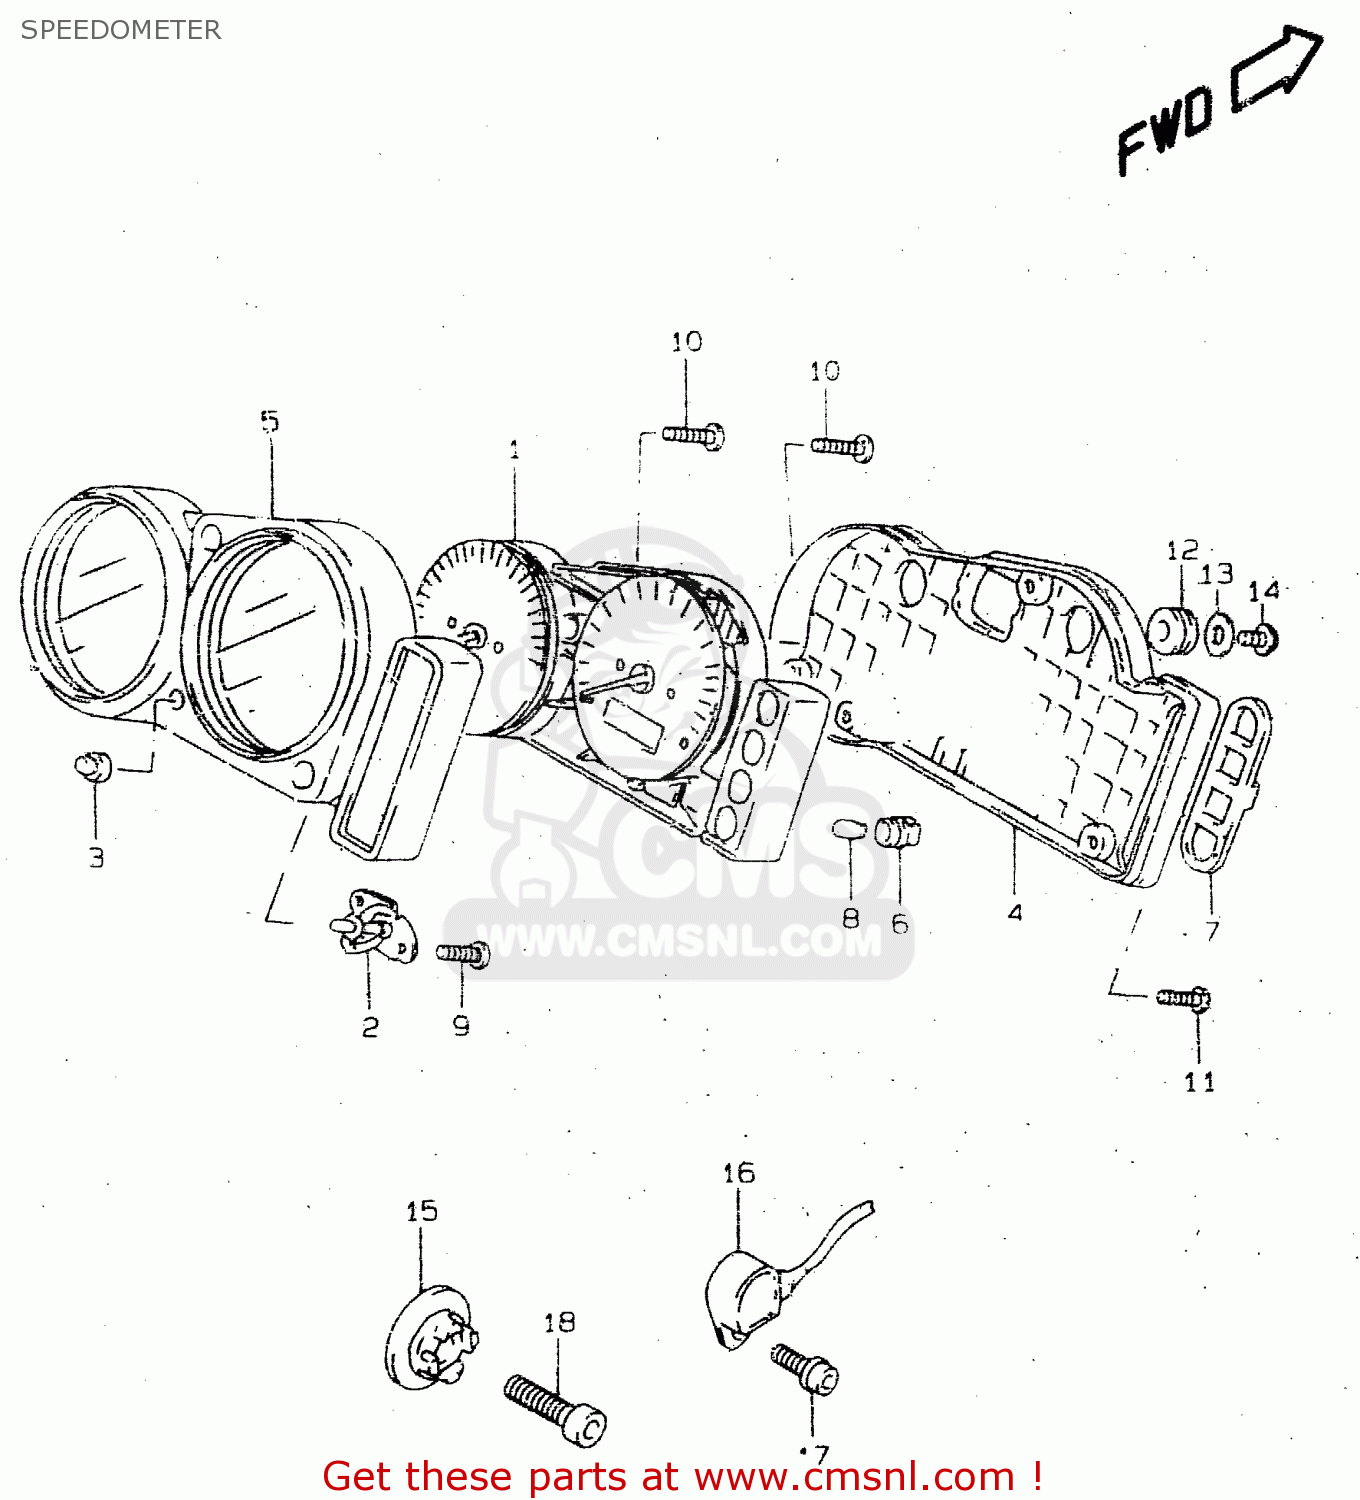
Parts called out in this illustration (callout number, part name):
1	SPEEDOMETER(KILO)
2	ATTACHMENT,SWITCH
3	SWITCH,GUM
4	CASE ASSY
5	VISOR,METER
6	SOCKET(T:6.5)
7	CAP,BLIND NO.2
8	BULB(12V1.7W,T6.5)
9	SCREW(3X10)
10	SCREW
11	SCREW
12	CUSHION,METER
13	WASHER(5.5X16X1.2)
14	SCREW
15	ROTOR,SPEED
16	SENSOR,SPEED
17	BOLT
18	BOLT
